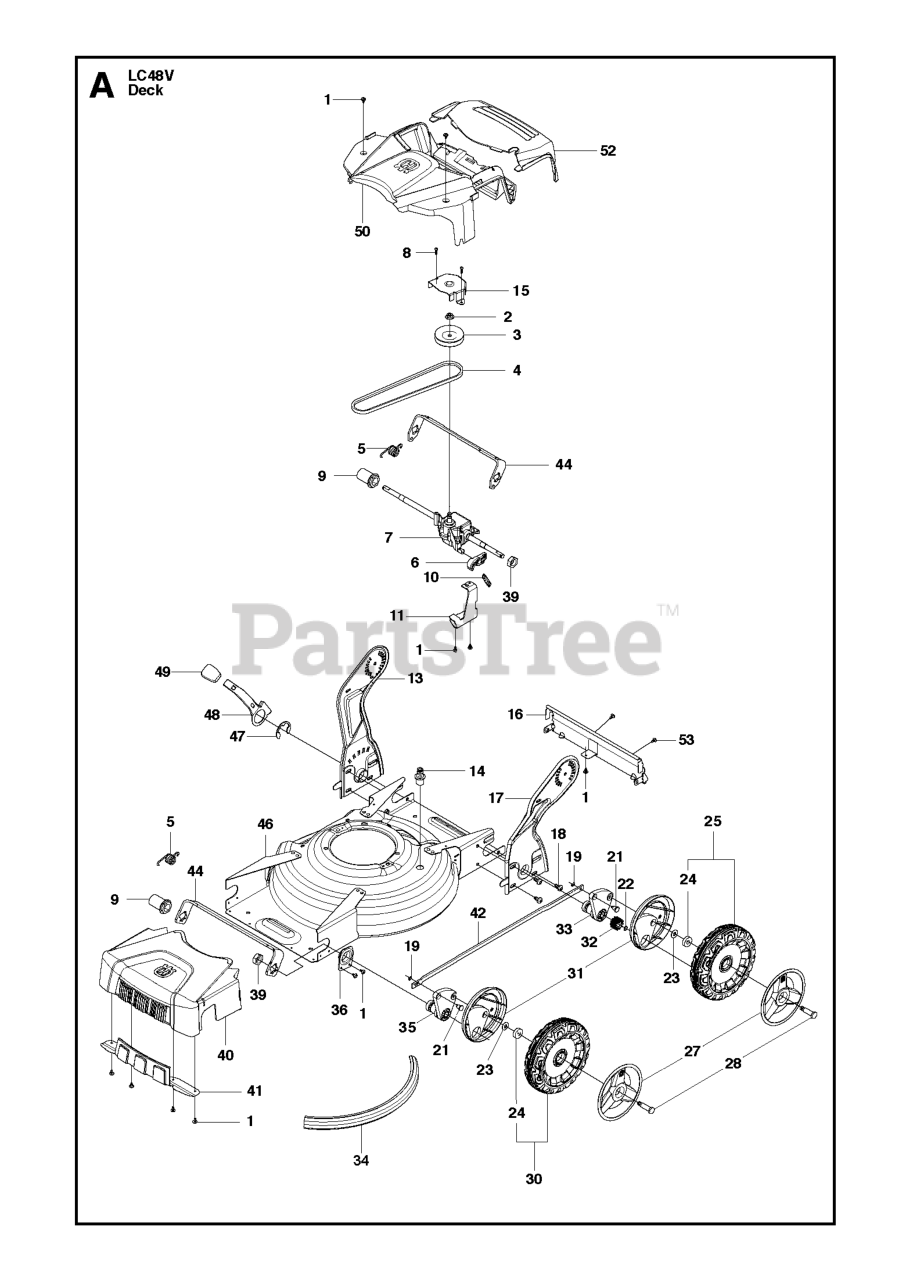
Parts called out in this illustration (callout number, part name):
1	SCREW ITXPANTT M5X10 ZPB (A00
4	BELT WRAPPED V-BELT Z 29.5
8	SCREW ITXPANT T50X16 ZN/FE (A
19	FASTENER
24	BALL BEARING
46	CHASSIS 48S A009 PAINTED
50	REAR COVER A009-2
53	SCREW ITXPANTT M5X10 ZPB (A00
